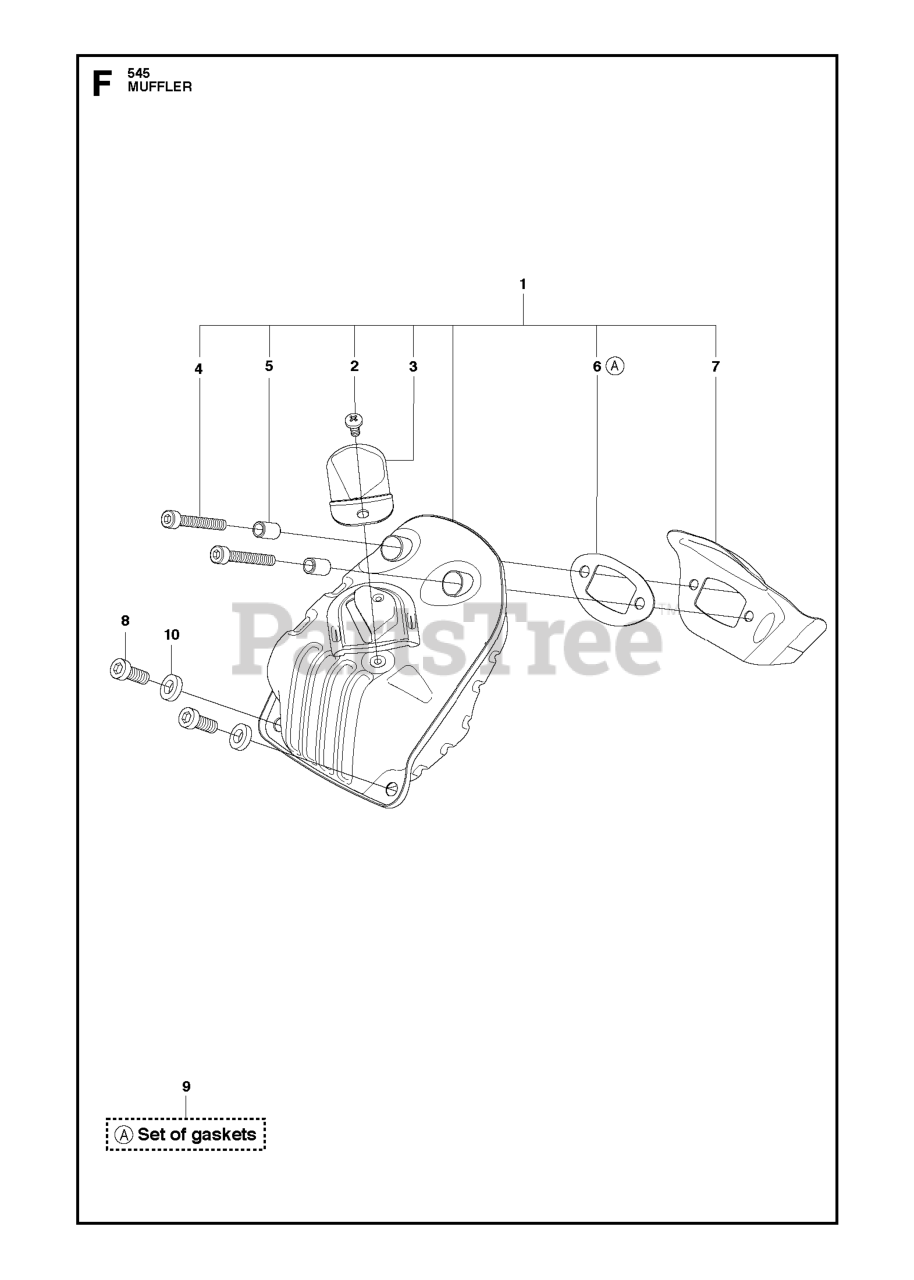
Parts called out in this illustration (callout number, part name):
1	MUFFLER KIT
2	SCREW
3	SPARK ARRESTER A004 50 CC
4	SCREW
5	SLEEVE
6	GASKET MUFFLER
7	HEAT DEFLECTOR
9	GASKET KIT
